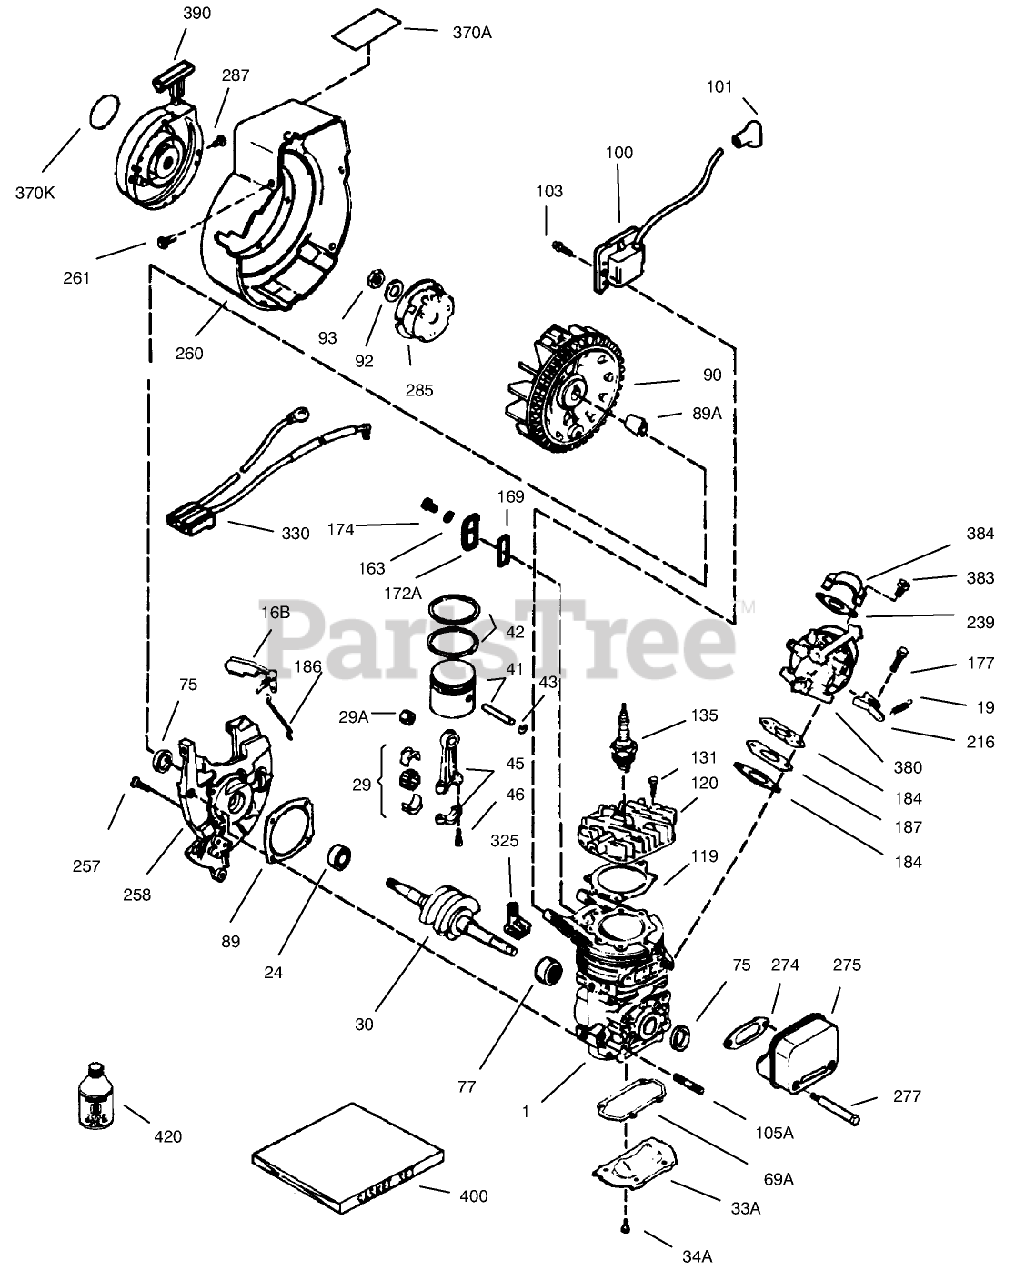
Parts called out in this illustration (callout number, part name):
1	Block Ass-y-Cylinder (Order short block if replacement is required)
16B	Vane-Air
19	Spring-Extention
24	Bearing-Ball
29	Needle Bearing and Liner Set (37 Needles)
29A	Bearing-Cartridge
30	Crankshaft
33A	Plate-Cover
34A	Screw (T-25, 10-24 x 1/2)
41	Piston (Incl. Ref. #43)
42	Ring Set
43	Ring-Retaning
45	Rod Assy.-Connecting (Incl. Ref. #3, 3A 3B)
46	Bolt-Rod, Connecting
69	Gasket-Cover, Cylinder
69A	Gasket-Plate, Cover
75	Seal-Oil
77	Bearing-Cartridge
89A	Blade (20 inch)
90	CARB BODY S
92	Washer-Belleville
93	Nut-Flywheel
100	Solid State
101	Cover-Spark Plug
103	Screw (T-15, 10-24 x 15/16)
119	Gasket-Head, Cylinder
120	Head-Cylinder
131	Screw (T-30, 1/4-20 x 3/4)
135	Spark Plug-Resistor (R C J 8Y)
163	Washer
169	Cover-Compression, Release
172A	Cover-Release, Compression
174	Screw (T-25, 10-24 x 1/2)
177	Screw (5/32 Allen, 1/4-20 x 1)
184	Gasket-Carburetor
186	Governor-Link
187	Spacer
216	Lever-Adjusting, Rpm
239	2060A77 WIZARD ROTA
257	Screw (T-30, 1/4-20 x 5/8)
258	Base Ass-y-Blower Housing (Incl Ref. #20)
260	Housing-Blower
261	Screw (1/4-20 x 1/2)
274	Gasket-Exhaust
275	Muffler (Incl. Ref. #274 277)
277	Screw (1/4-20 x 2-3/4)
285	Cup-Starter
287	Screw (8-32 x 21/64)
325	Clip-Wire
330	Harness-Wire
370A	Decal-Lubrication
370K	Decal-Tecumseh Logo for Top of Recoil Starter
380	Carburetor (Incl. ref. #184)
383	Baffle-Carburetor
384	Screw (T-25, 10-32 x 5/8)
390	Rewind Starter ASM
400	Gasket Set
422	2-Cycle Oil (8oz)
